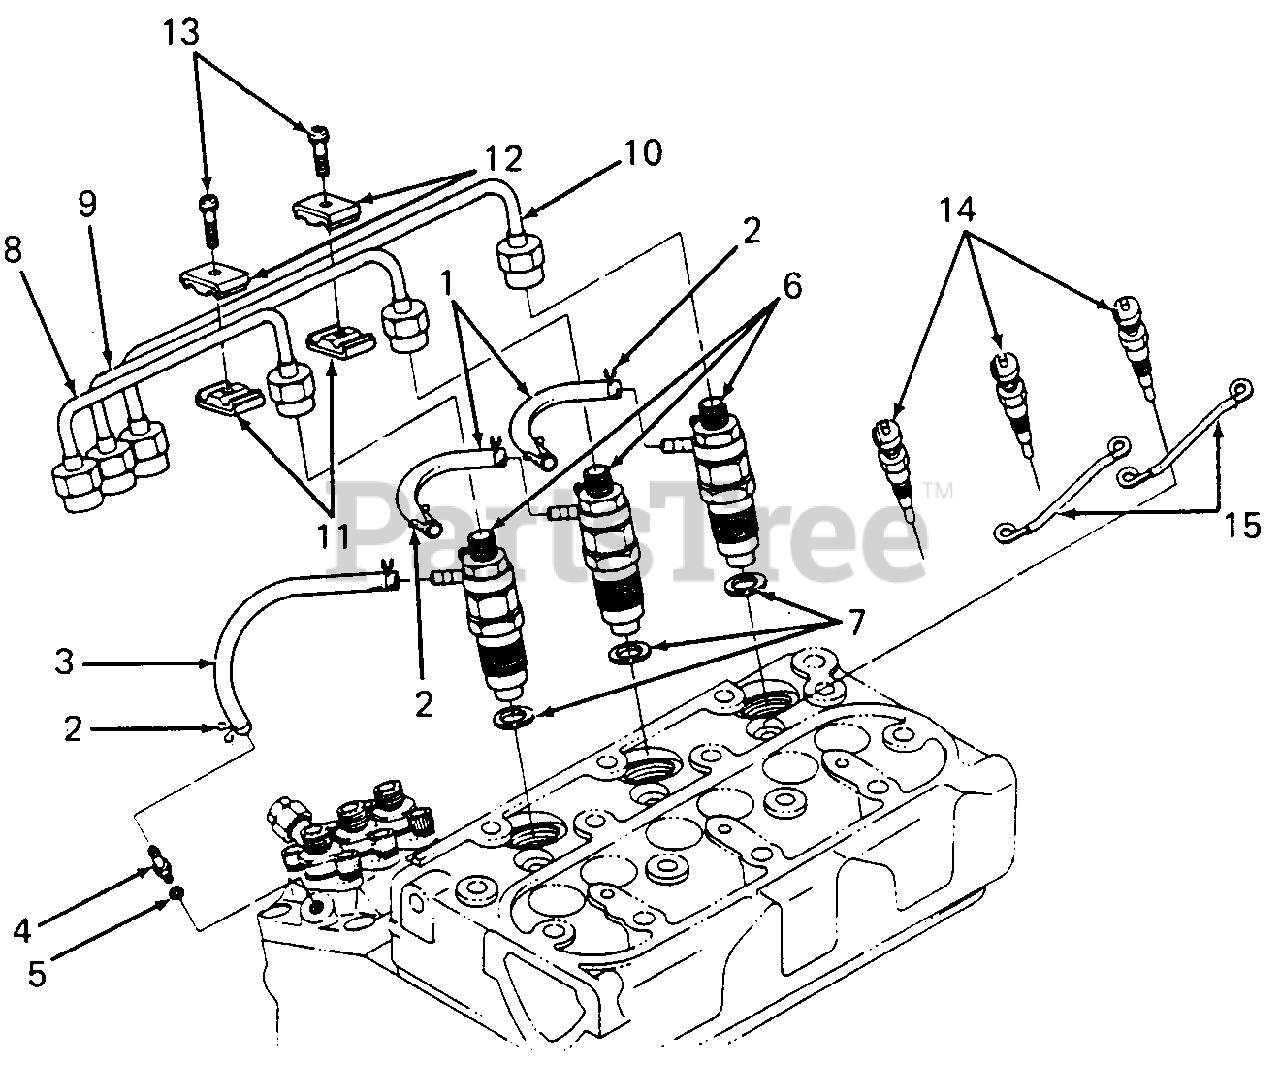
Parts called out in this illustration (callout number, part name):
1	Pipe, Overflow
3	Pipe, Overflow
6	Nozzle, Injection
7	Washer
8	Pipe, Injection - 1
9	Pipe, Injection - 2
10	Pipe, Injection - 3
11	Clamp, Pipe - 1
12	Clamp, Pipe - 2
13	Screw w/Washer
14	Plug, Glow
15	Wire, Glow Plug
